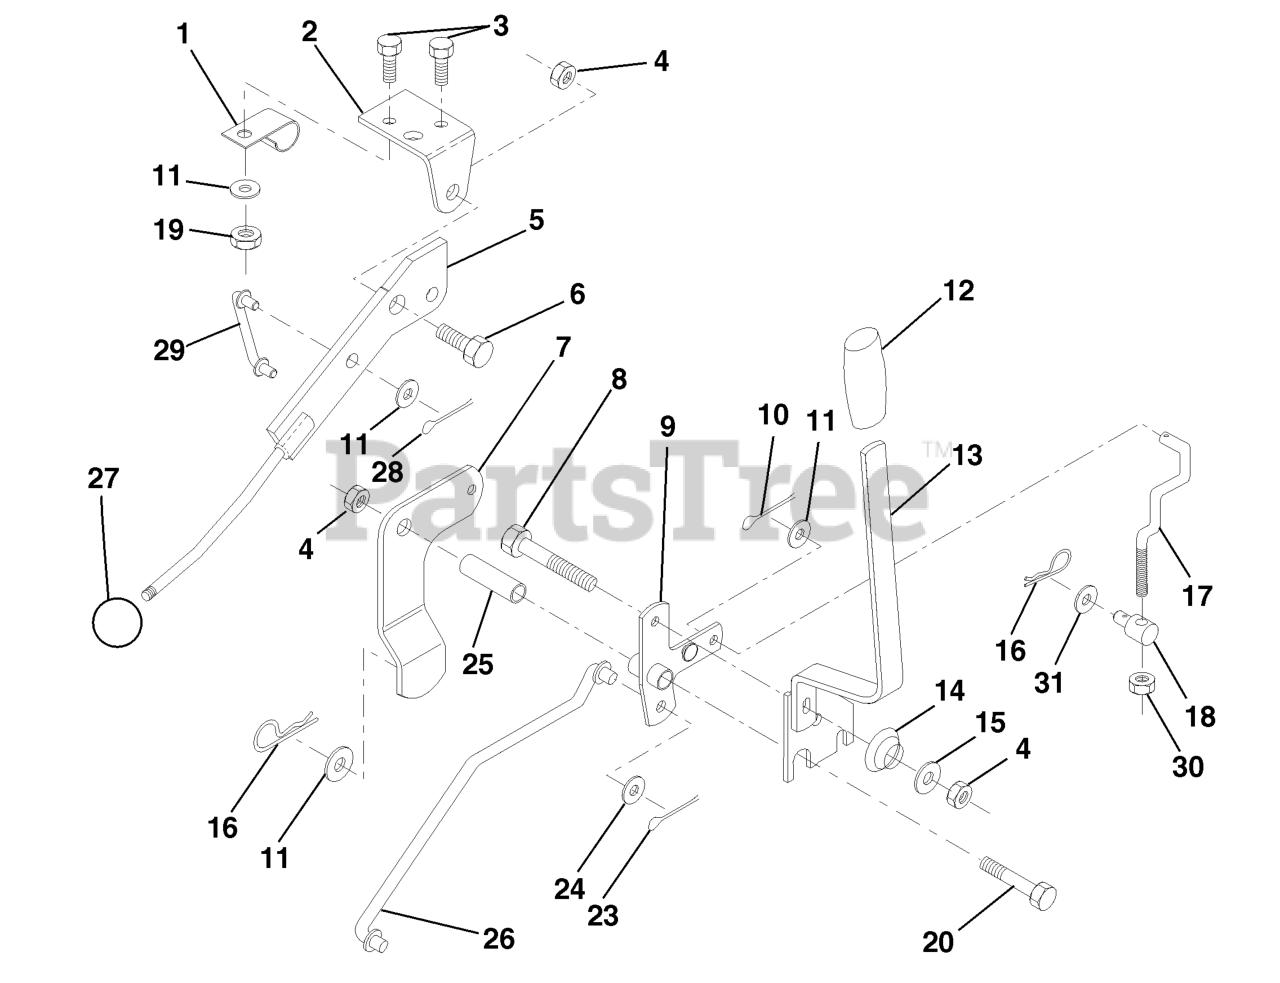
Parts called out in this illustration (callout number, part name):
1	CLIP,INSULATOR
2	BRKT CLUTCH
3	BOLT
5	CLUTCH LEVER
6	BOLT, SHOULDER LT
7	ASSEMBLY MOWER CLUTCH ARM
9	BELLCRANK,LIFT
10	COTTER PIN
11	WASHER
12	HANDLE GRIP
13	LIFT HANDLE ASSY
14	SPRING COMPRESSIO
15	WASHER T
16	SPRING TI
17	LINK LIFT FRT
18	TRUNNION.ADJUSTABLE.3/8-16
19	Nut, Crownlock 1/4-20
23	PIN COTTER
24	WASHER GT
25	TUBE SPACER
27	KNOB T (3/8 HOLE)
28	COTTER PIN
29	LINK MOWER CLUTCH
30	NUT
31	WASHER
